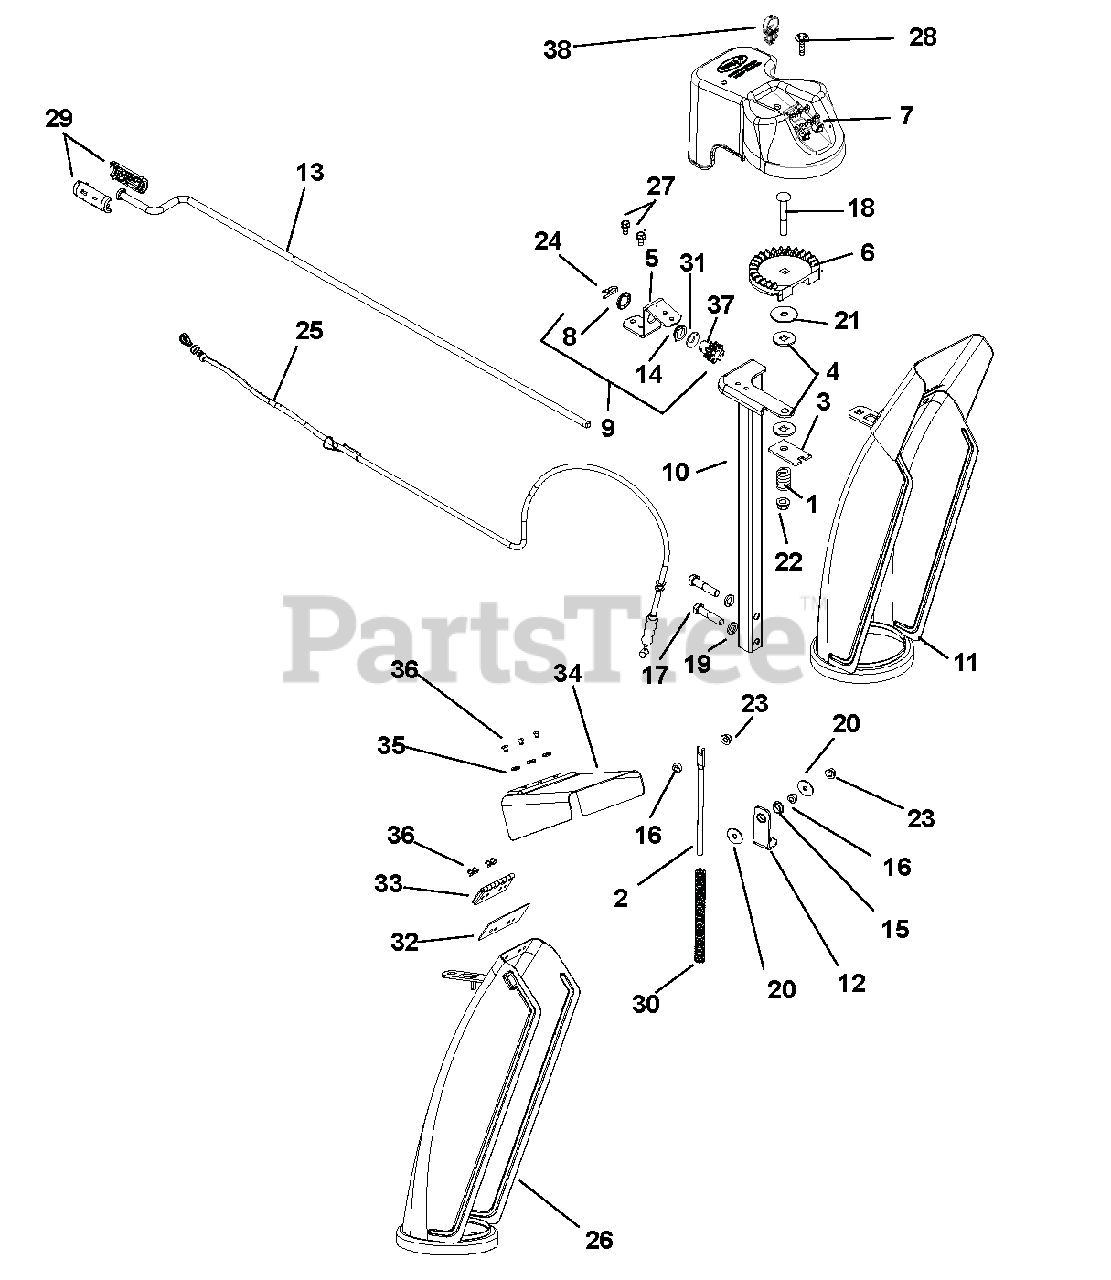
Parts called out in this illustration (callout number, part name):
1	SG-COMP .187X.56X1.62
2	ROD, DEFLECTOR CAP
3	PLATE, FRICTION
4	FRICTION WASHER
5	BRACKET, PINION GEAR
6	CHUTE GEAR
7	GEAR COVER ASSY SM SHEAR BOLT
8	PUSHNUT .625
9	PINION GEAR W/BRACKET
10	CHUTE PEDESTAL, TALL COMPACT
11	CHUTE, DISCHARGE W/REM.CAP,DEC
12	BRACKET, CABLE ANCHOR
13	ROD, CHUTE CRANK, COMP&SNOTEK
14	BUSHING, POLYLINER-.63 SNAPIN
15	BUSHING, POLYLINER-.50 SNAPIN
16	BSHG-SLV .265X.500X.219
17	@BLT-HEX .38-16X1.75 GR5 YWZC
18	@BLT-RDHDSQNK .38-16X2.50 G5YZ
19	@WSHR-LK .38X.094 REG YWZC
20	WSHR-FL-STL .281X1.000X.063
21	@WSHR-FL-STL .406X1.25X.10 ZC
22	@NUT-LK-TOP-FLG .38-16 YWZC
23	@NUT-LK-CTR-FLG .25-20 YWZC
24	PIN, SPRING CLIP
25	CABLE, DEFLECTOR - COMPACT
26	CHUTE, COMPACT-TALL W/REMOTE
27	SCR-TAP .25-20X.50 HWH TR YWZ
28	SCR-TAP .25-20X.50 LGHWH TR YZ
29	KNOB, CHUTE CRANK - SNAP BLK
30	SG-COMP .08X.40X6.50 14#/IN
31	WSHR-THRST .625 X 1.0 X .03
32	CAP SEAL 5.25
34	CAP, COMPACT-W/REMOTE
35	WSHR-FL-STL .196X.500X.06 YZ
36	RVT-POP .187 YZ
37	PINION GEAR - CHUTE
38	CLIP, CABLE GUIDE
